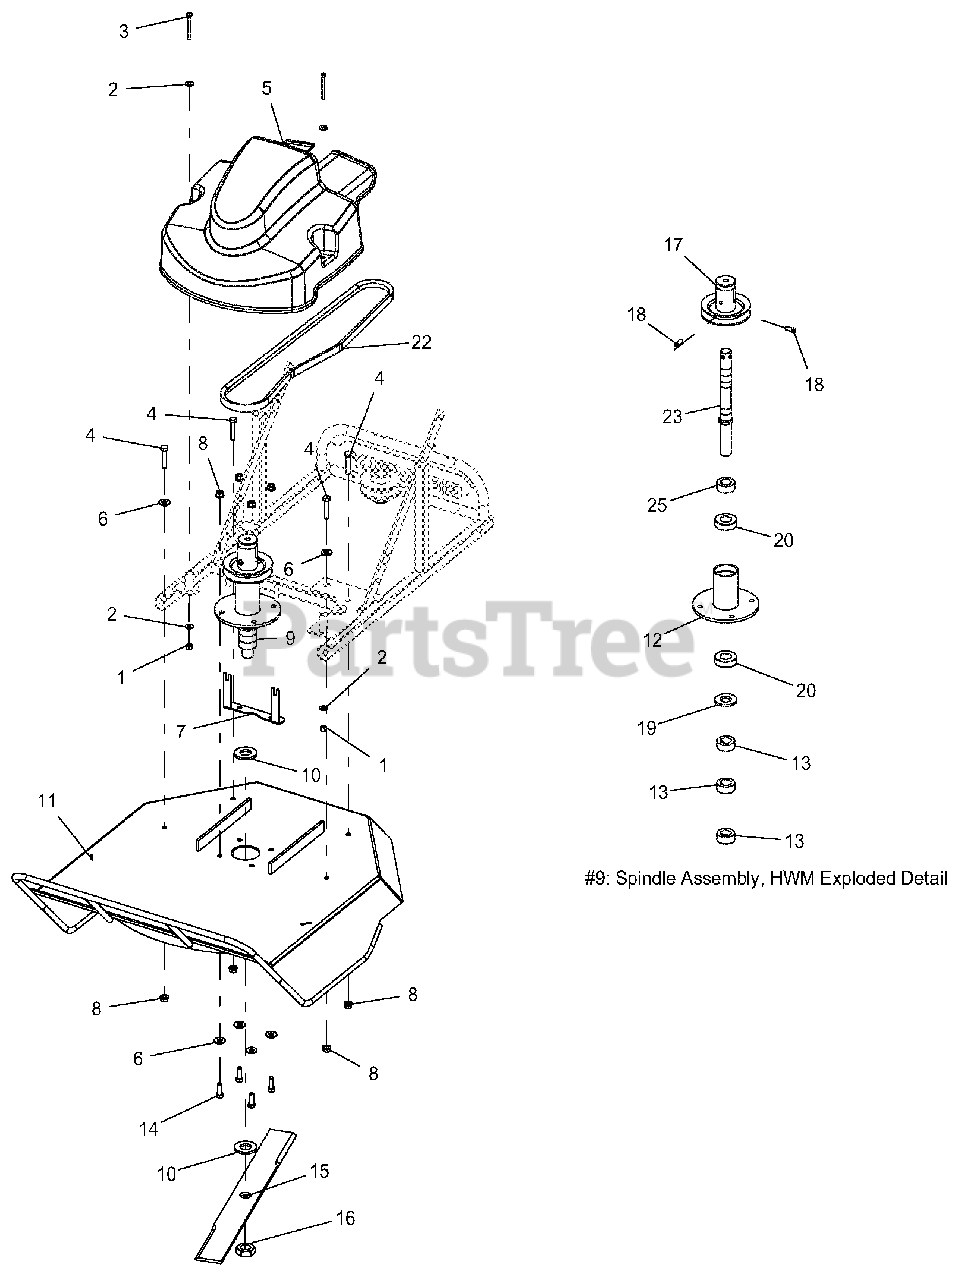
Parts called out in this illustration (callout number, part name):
1	NUT-LK-NYL .250-20 YWZC
2	WSHR-FL-STL.312X.734X.065 YWZ
3	BLT-HEX .25-20X2.25 GR5 YWZC
4	BLT-HEX .38-16X1.75 GR5 YWZC
5	COVER, PLASTIC BELT-HIGH WHEEL
6	WSHR-FL-STL.438X1.00X.083 YWZC
7	WLDMT, HWM SPINDLE BELT FINGER (BLACK)
8	NUT, LK-TOP-FLG .38-16 YWZC
9	SPINDLE ASSY, HWM
10	1"USS WASHER HARD NO PLA
11	WMT- DECK, BRUSHCUTTER (RED)
12	WMT-SPINDLE, HW MOWER (BLACK)
13	LOCKING COLLAR 1IN
14	BLT-HEX .38-16X1.00 GR5 YWZC
15	BLADE, BRUSH MOWER 24"
16	JAM NUT 1-14 NF
17	DOUBLE BLADE SHAFT PULLEY
18	SCR, SET - .31-18 X .75 SQCUPHT
19	1"USS WASHER HARD NO PLA
20	BEARING 1.00 ID X 2
22	V-BELT, 5L-WRAPPED
23	WMT-SPINDLE SHAFT, HWM
25	LOCKING COLLAR 1IN
